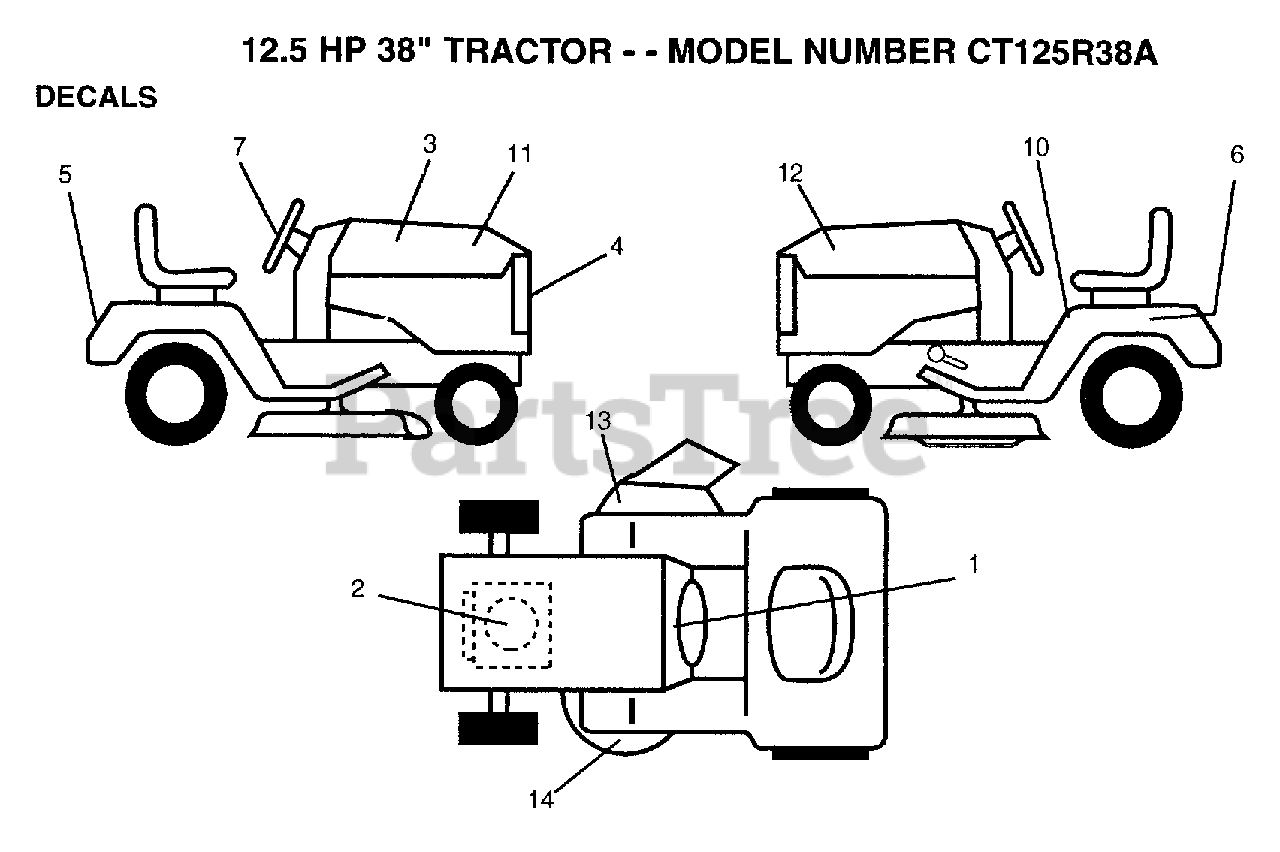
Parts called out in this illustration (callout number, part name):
1	DECAL INST ENGINE
3	DECAL.HOOD.12.5
4	DECAL.GRILLE
5	DECAL.FENDER
6	DECAL
7	DECAL.STG.WHL.INS
10	DECAL
11	DECAL.HOOD.RH
12	DECAL.HOOD.LH
13	"DECAL, WARNING"
